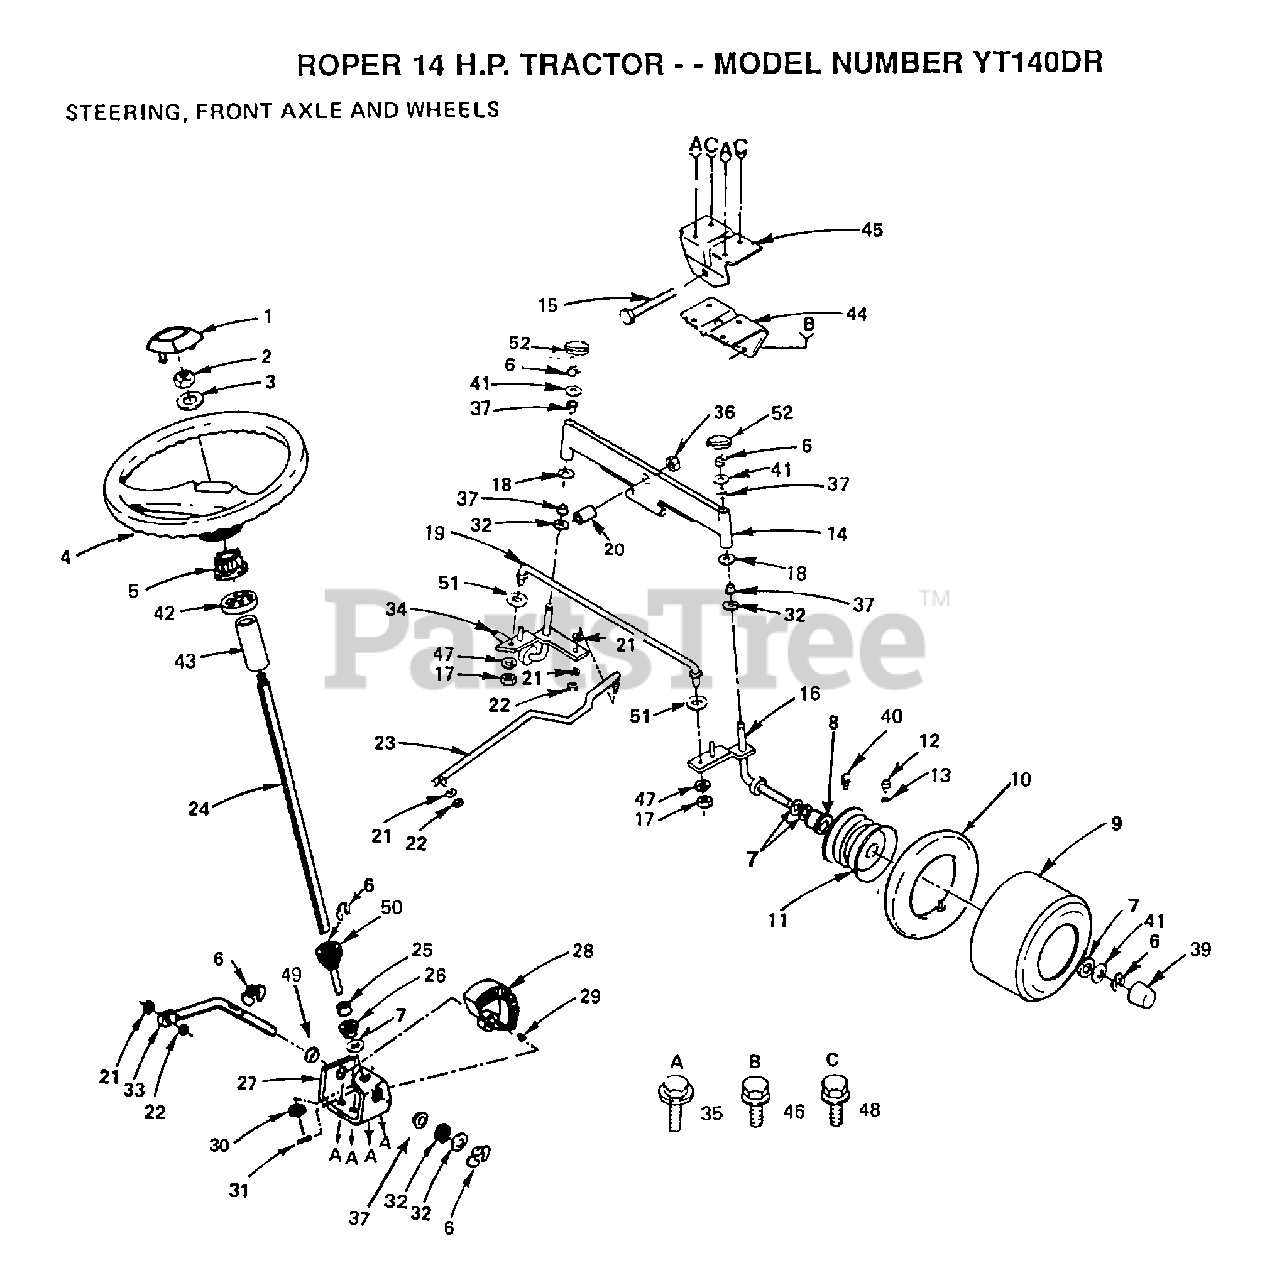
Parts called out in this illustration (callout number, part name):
1	INSERT STEERING
3	WASHER
5	ADAPTER LT
6	RING
7	WASHER
8	"FLANGE, BEARING"
10	TUBE.5.3/4.5/6
12	VALVE STEM LT
13	VALVE CAP
14	FRONT AXLE
15	BOLT LT
17	NUT.LOCK.5/16-24
18	WASHER
19	ROD TIE
20	BEARING
21	LOCKWASHER
23	LINK-DRAG LT
24	STEERING SHAFT T
25	SHAFT SPACER LT
26	BUSHING
28	GEAR.SECTOR.HYT
29	KEY-WOODRUFF LT
32	WASHER .T
33	ROD STEERING T
34	SPINDLE-LH LT
35	SCREW
36	"NUT-LOC,FLANGE LT"
37	COL. SRTG. BEAR.
39	HUB CAP
40	FITTING LT
41	WASHER
44	SUPPORT.SADDLE.FT
45	SUPPORT-SADDL T
46	SCREW LT
47	LOCKWASHER
48	SCREW GTV
49	NYLINER T
50	GEAR PINION T
51	WASHER M
52	CAP
